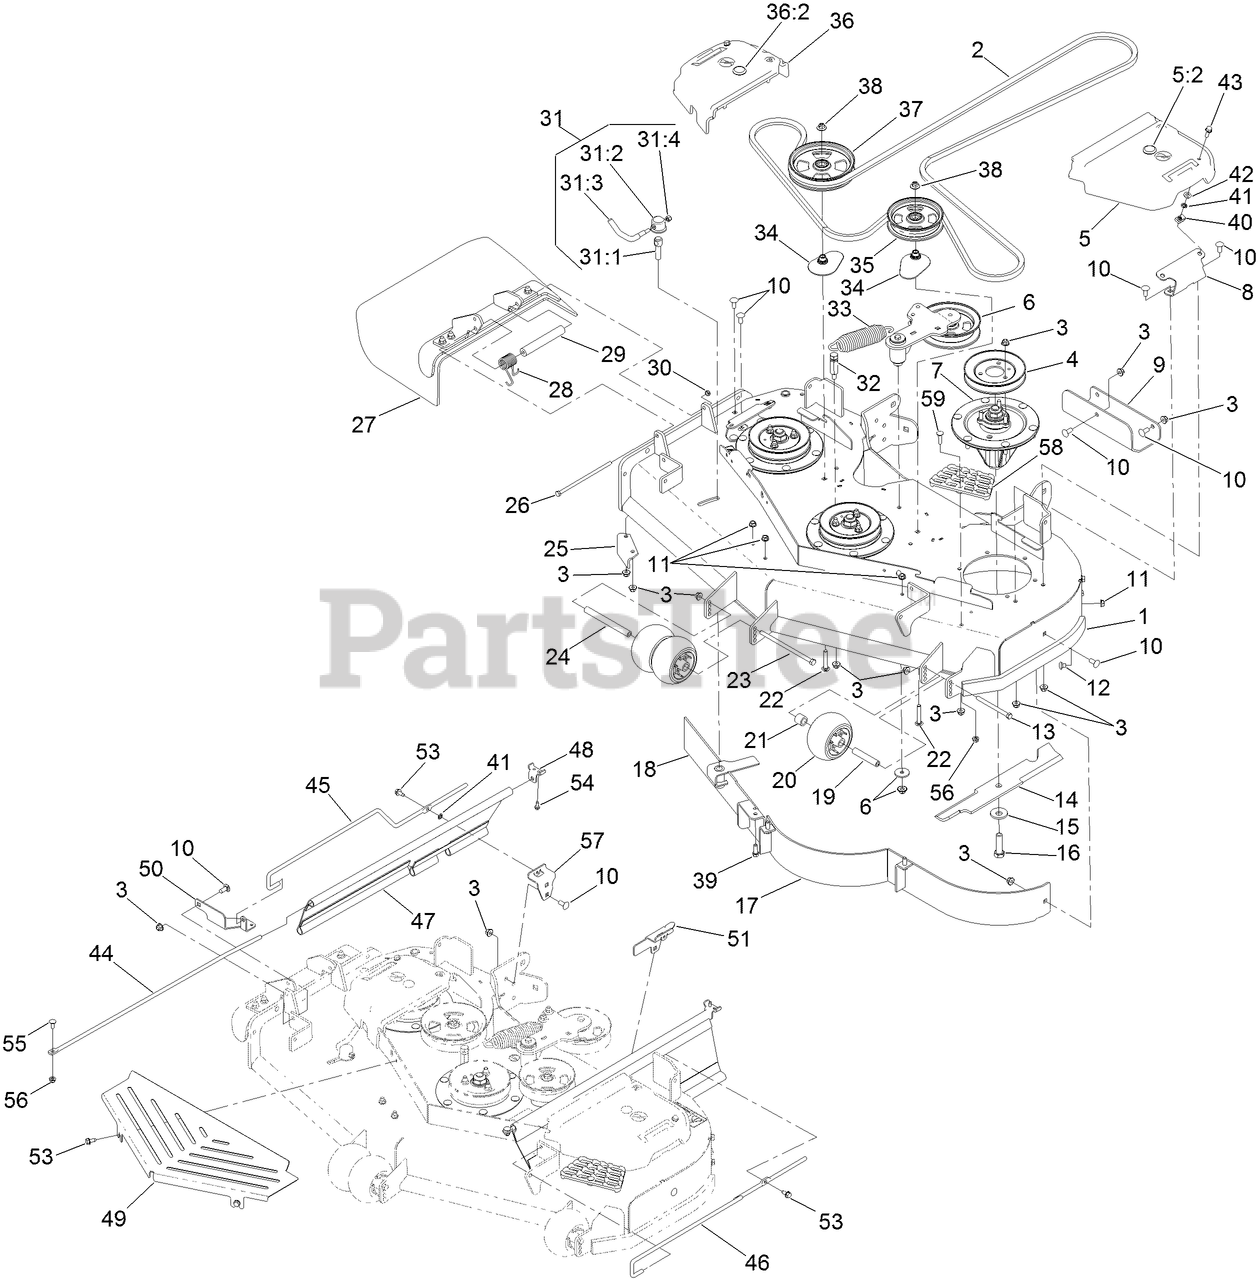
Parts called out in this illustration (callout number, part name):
1	DECK DECAL ASM
2	BELT-V
3	NUT-HF, NI
4	PULLEY
5	LH BELT COVER ASM
5:2	PLUG-PLASTIC
6	IDLER ARM ASM
7	SPINDLE ASM
8	BRACKET-COVER, BELT
9	PLATE-SKID
10	SCREW-CARR
11	NUT-HHF, WHIZ
12	SCREW-CARR
13	SCREW-HH
14	BLADE-16.5 INCH (HIGH FLOW)
15	WASHER-BLADE BOLT, HEAVY
16	SCREW-BLADE
18	ADJUSTABLE BAFFLE ASM
19	TUBE-SPANNER
20	ROLLER-SCALP, ANTI
21	TUBE-SPACER
22	BOLT-CARR, SHORT NECK
23	SCREW-HH
24	SPACER-WHEEL
25	BAFFLE-DISCHARGE
26	SCREW-HH
27	RUBBER DEFLECTOR ASM
28	SPRING-TORSION
29	SPACER
30	NUT-LOCK, NI
31	LEVER ASM
31:1	SCREW-LOCK
31:2	CAP-LOCK
31:4	NUT-LOCK, NI
32	ANCHOR-SPRING, TALL
33	SPRING-EXTENSION
34	SPACER-PULLEY
35	PULLEY-IDLER,FLAT
36	RH BELT COVER ASM
36:2	PLUG-PLASTIC
37	PULLEY-IDLER, FLAT
38	NUT-FLANGE, NI
40	NUT-U
41	NUT-PUSH
42	WASHER-THRUST
43	SCREW-HHF
44	ROD-SUPPORT, UPPER
45	ROD-SUPPORT, LOWER (RH)
46	ROD-SUPPORT, LOWER (LH)
47	GUARD-SIDE
48	BRACKET-MOUNTING, UPPER
49	SHIELD-FRONT
50	BRACKET-MOUNTING, FRONT
51	BRACKET-MOUNTING, REAR (LH)
53	SCREW-HWHTF
54	SCREW-HWH
55	SCREW-CARR
56	NUT-HF, NI
57	BRACKET-MOUNTING, REAR (RH)
58	STEP-DECK
59	SCREW-CARR
